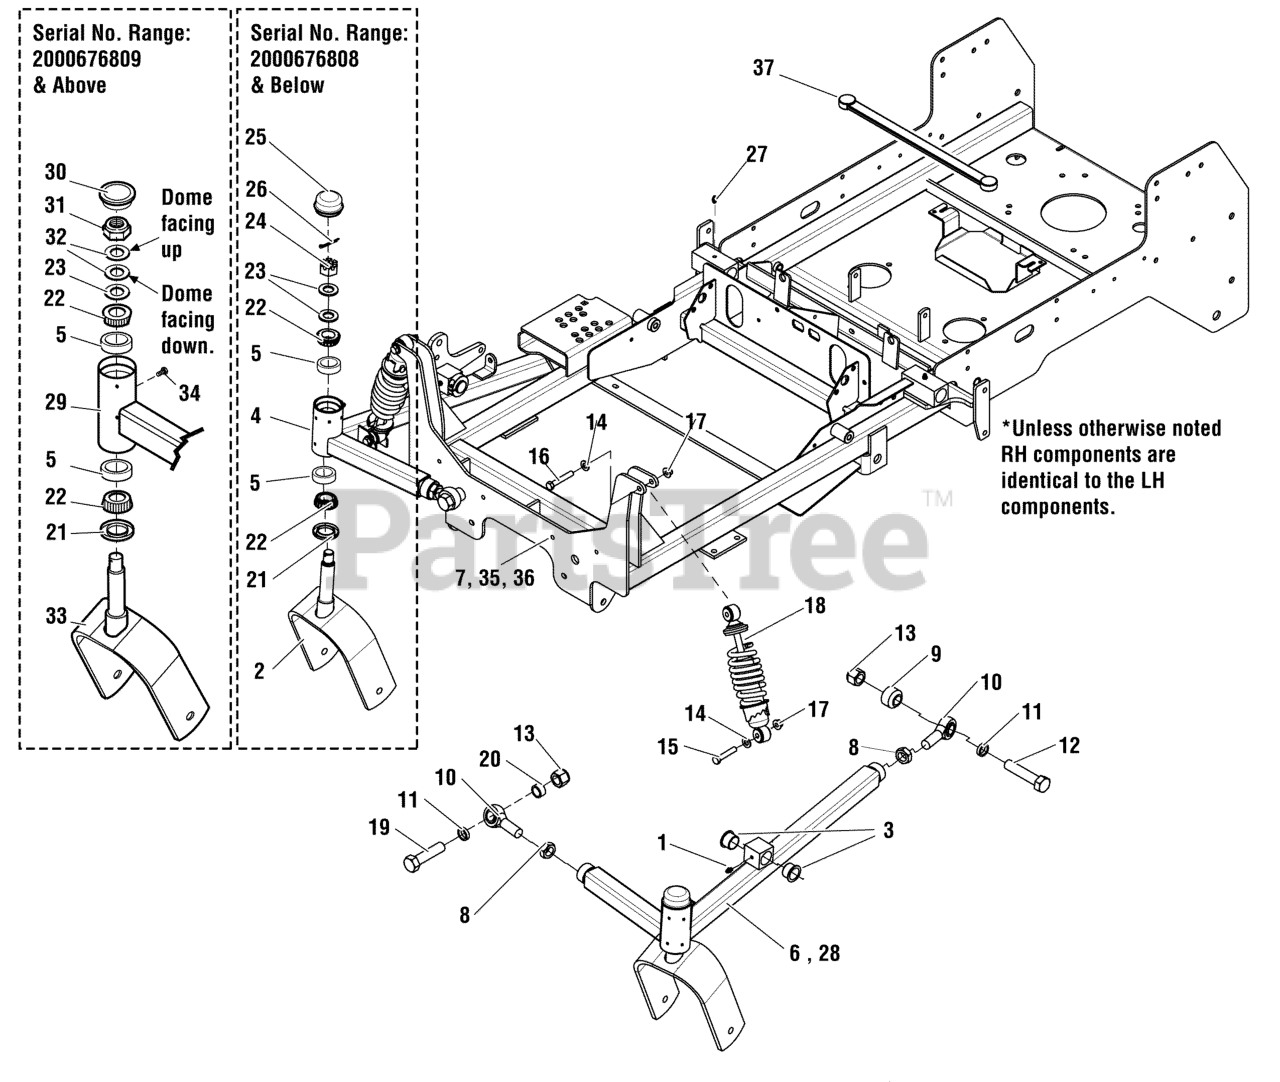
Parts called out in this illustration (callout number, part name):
1	GREASE FITTING, 1/4-28 STRAIGHT
2	WELD, CASTER YOKE
3	BUSHING, 1.00X1.13X.75, PLA
4	WELD, FRONT A-ARM - RH - RED
5	BEARING CUP
6	WELD, FRONT A- ARM - LH - RED
7	WELD, MAIN FRAME, IS2000 - RED
8	NUT, HEX JAM, 3/4-16
9	SPACER, .75 X 1.50 X 1.00
10	BALL JOINT, 3/4-16 MALE
11	SPACER, .76 X 1.00 X .25
12	BOLT, 3/4-16 X 3-1/2" YZ GD5
13	NUT, 3/4-16 HEX NYLON LOCK
14	WASHER, 3/8 SAE
15	BOLT, 3/8-16 X 2, GD5, CZ
16	BOLT, 3/8-16 X 2-1/4" GD5 CZ
17	NUT, 3/8-16 HEX NYLOCK FLANGE
18	SHOCK ABSORBER
19	BOLT, 3/4-16 X 3" YZ GD5
20	SPACER, .76 X 1.00 X .50
21	SEAL, GREASE
22	BEARING, TAPPERD ROLLER, 1"
23	WASHER, 3/4 SAE
24	NUT, 3/4-16 HEX SLOTTED
25	CAP, DUST
26	PIN, COTTER, 1/8 X 1-1/4
27	GREASE FITTING, 1/4-28 45 DEGREE
28	WELD, FRONT A-ARM - LH -RED
29	WELD, FRONT A-ARM - RH -RED
30	CAP, GREASE, LOW PROFILE
31	NUT, 3/4-16, HEX JAM NYLON LOCK
32	BELLEVILLE WASHER, 1.500 X .755
33	WELD, CASTER YOKE - RED
34	BOLT, 1/4-28 X 1/2, GD5 YZ
35	WELD, MAIN FRAME, IS2000 - RED
36	WELD, MAIN FRAME, IS2000/COBALT - RED
37	STRAP-BLACK RUBB
